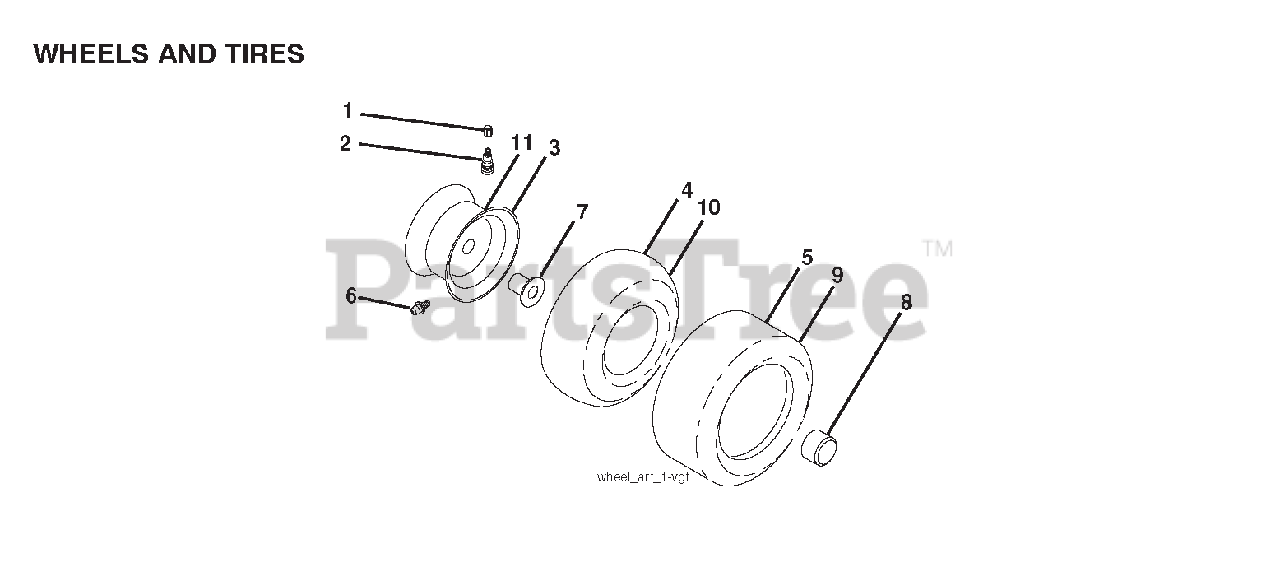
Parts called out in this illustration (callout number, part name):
1	CAP.VALVE.TIRE
2	STEM.VALVE
3	RIM ASSEMBLY 6" FRONT
4	TUBE.INNER.FRONT.#35060
5	TIRE.F.TS.15 X 6.0 - 6.SERVICE
6	FITTING, GREASE
7	BEARING FLANGE
8	CAP AXLE (FRONT WHEEL ONLY)
9	TIRE.R.TS.20 X 8-8.C.SERVICE
10	TUBE, REAR
11	RIM ASSEMBLY 8" REAR
